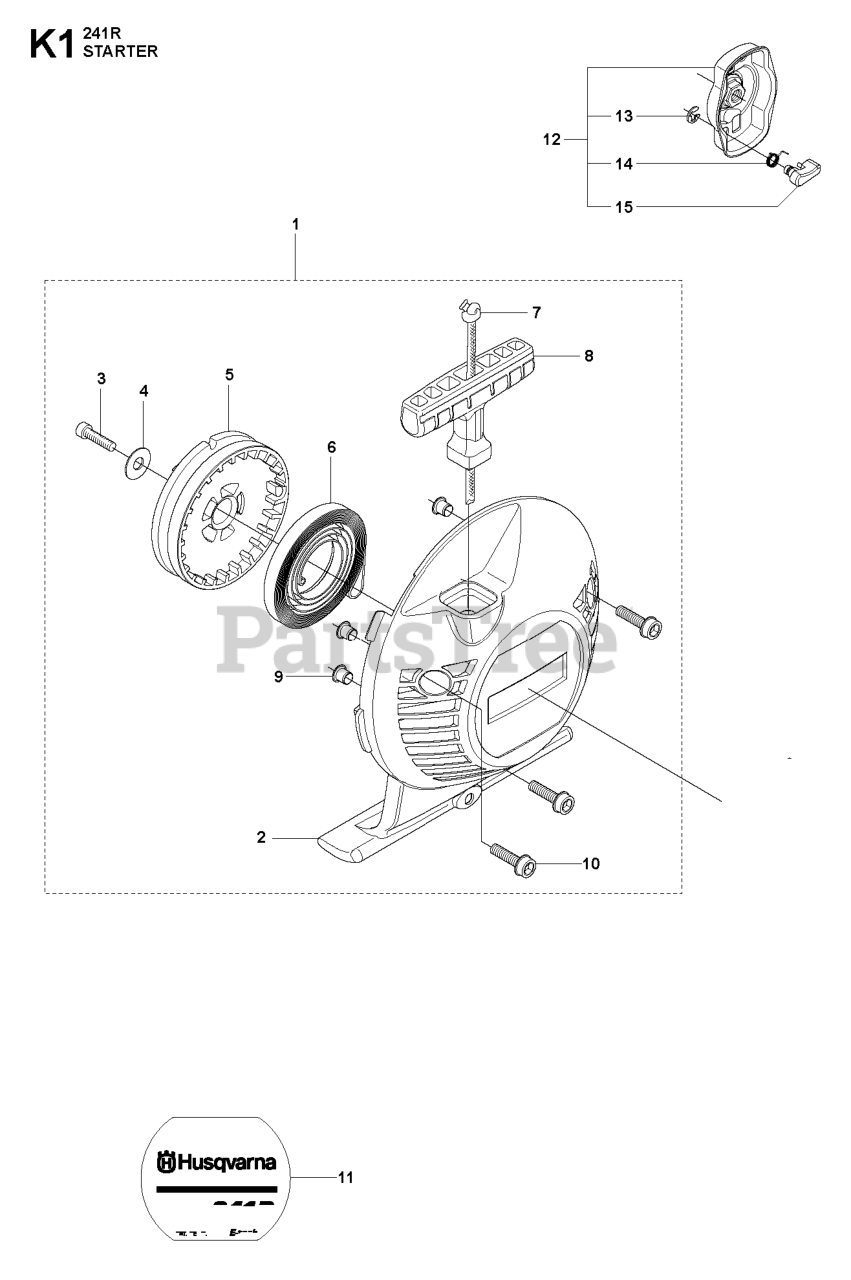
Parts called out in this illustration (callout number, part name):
1	RP STARTER ASSY
2	STARTER HOUSING SET
5	STARTER PULLEY
6	STARTER SPRING
7	STARTER ROPE
8	STARTER HANDLE
10	SCREW IHSCFM
12	PAWL
15	STARTER PAWL
